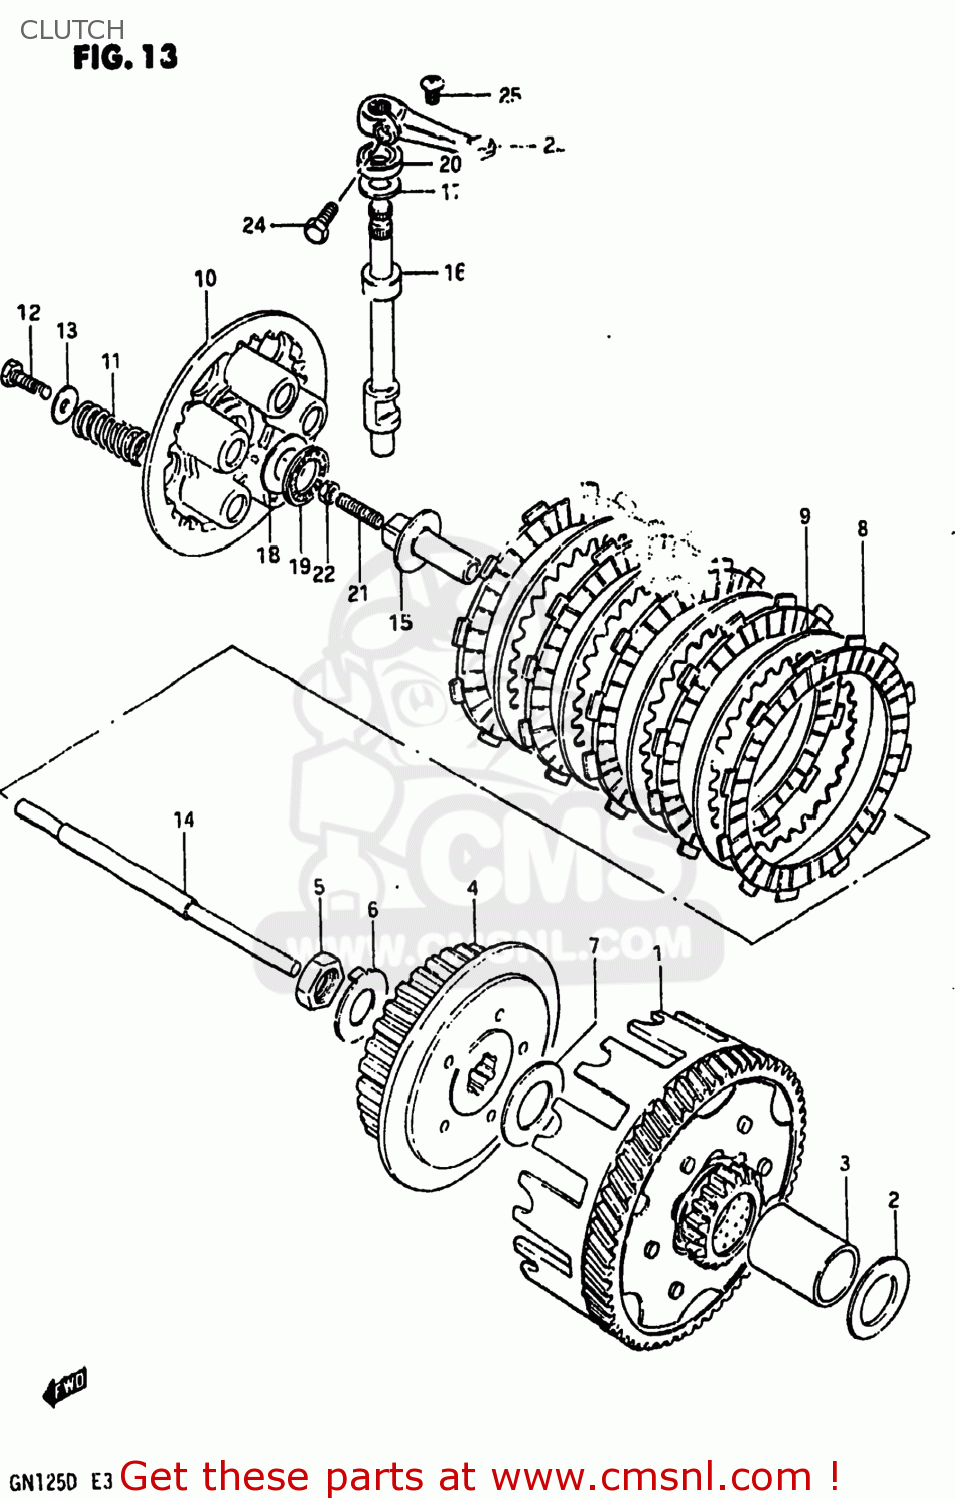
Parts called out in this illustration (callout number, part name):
1	GEAR ASSEMBLY,PRIMARY DRIVE
2	WASHER
3	SPACER
4	HUB,CLUTCH SLEEVE
5	NUT
6	WASHER
7	WASHER
8	PLATE,CLUTCH DRIVE
9	PLATE,CLUTCH DRIVEN (NAS)
10	PLATE,CLUTCH PRESSURE
11	SPRING
12	BOLT(5X16)
13	WASHER(5.5X16X1.2)
14	ROD,CLUTCH PUSH
15	PIECE,CLUTCH PUSH
16	CAMSHAFT,CLUTCH RELEASE
17	WASHER,THRUST
18	WASHER
19	BEARING(15X28X2)
20	OIL SEAL
21	SCREW
22	NUT 6MM
23	ARM,CLUTCH RELEASE
24	BOLT, UPPER
25	SCREW
